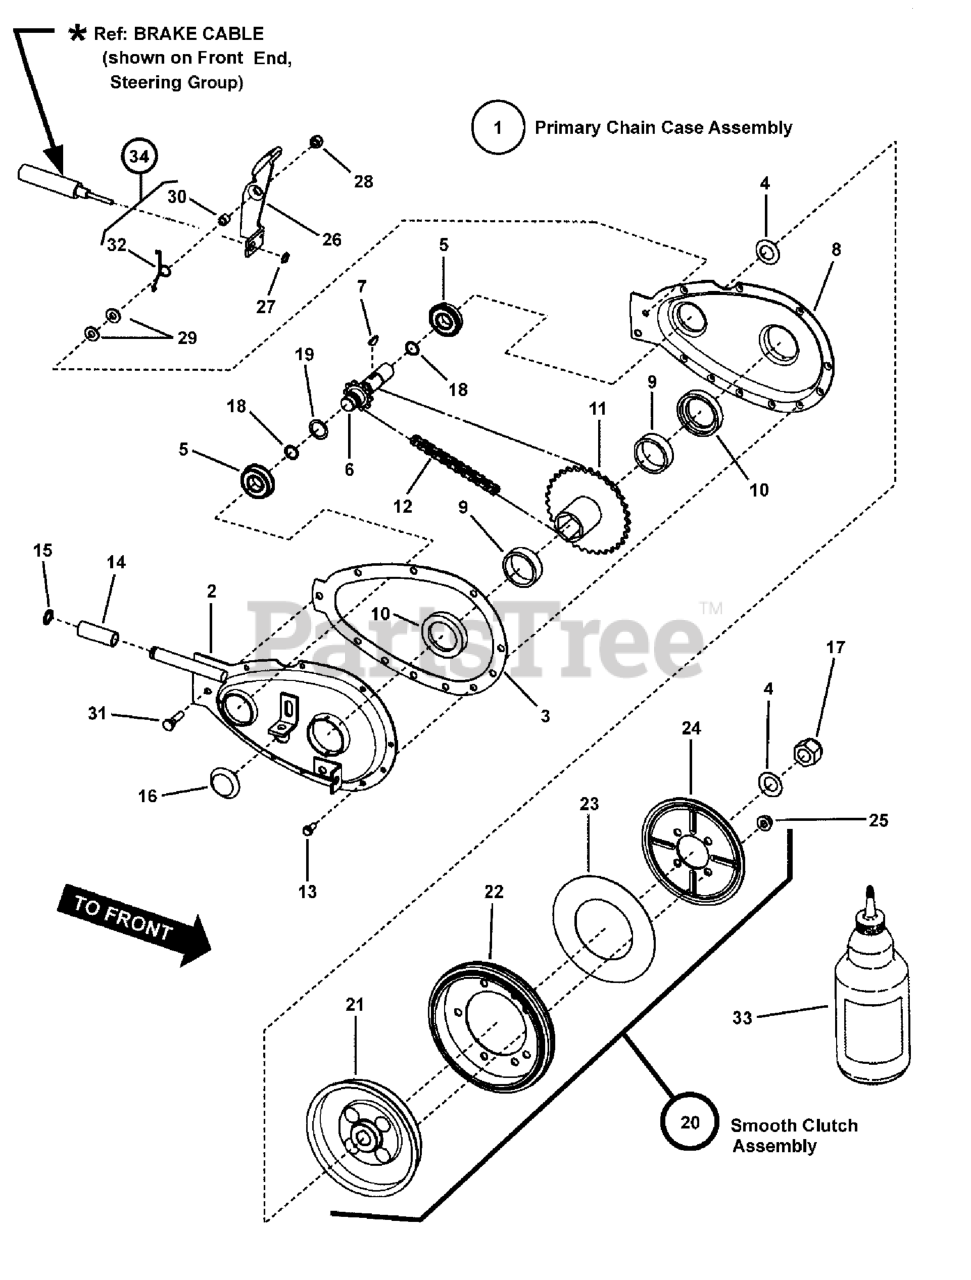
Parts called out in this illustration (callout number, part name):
1	ASSEMBLY, Primary Chain Case
2	WELDMENT, Primary Chain Case Half, Right Hand
3	GASKET, Primary Chain Case
4	WASHER, 5/8" Belleville
5	BEARING, .625 x 1.37 x .435
6	WELDMENT, Sprocket & Shaft
7	KEY, #5 Woodruff
8	PRIMARY CHAIN CASE HALF, Left Hand
9	BEARING, Needle 1.355" ID x 1.6245" OD x .5" Wide
10	THRUST WASHER, Nylon
11	WELDMENT, Hub & Sprocket
12	CHAIN, 46 Pitch (#35 Endless)
13	SCREW, 10-24 x 1/2" Hex Washer Self-Tap
14	ROLLER, 1-3/8 Long
15	RING, 1/2" External Retaining (Heavy Duty)
16	PLUG, 3/4" Cup Insert
17	NUT, 5/8-18 Hex Nyloc
18	O-RING, 1/2 x 5/8"
19	WASHER, Shim .625 x .875
20	ASSEMBLY, Smooth Clutch, non-asbestos
21	HUB, Driven Disc Assembly
22	DISC, Driven (rubber tire bonded to rim)
23	THRUST WASHER
24	PLATE, Drive Disc
25	NUT, 5/16-24 Hex Flange Lock
26	ASSEMBLY, Brake Lever (Includes brake pad & rivet)
27	RING, 3/8" External Retaining
28	NUT, 1/4-28 Hex Top Lock
29	WASHER, .28 x .63 x .06 Flat, GR 5
30	SPACER, Brake Arm Pivot (.418/.403 long)
31	SCREW, 1/4-28 x 1" Hex Head Cap, (Washer Face) GR 5
32	SPRING, Torsional Brake Return
33	GREASE, Transmission (Use 2 oz. Maximum)
34	KIT, Brake Return Replacement
